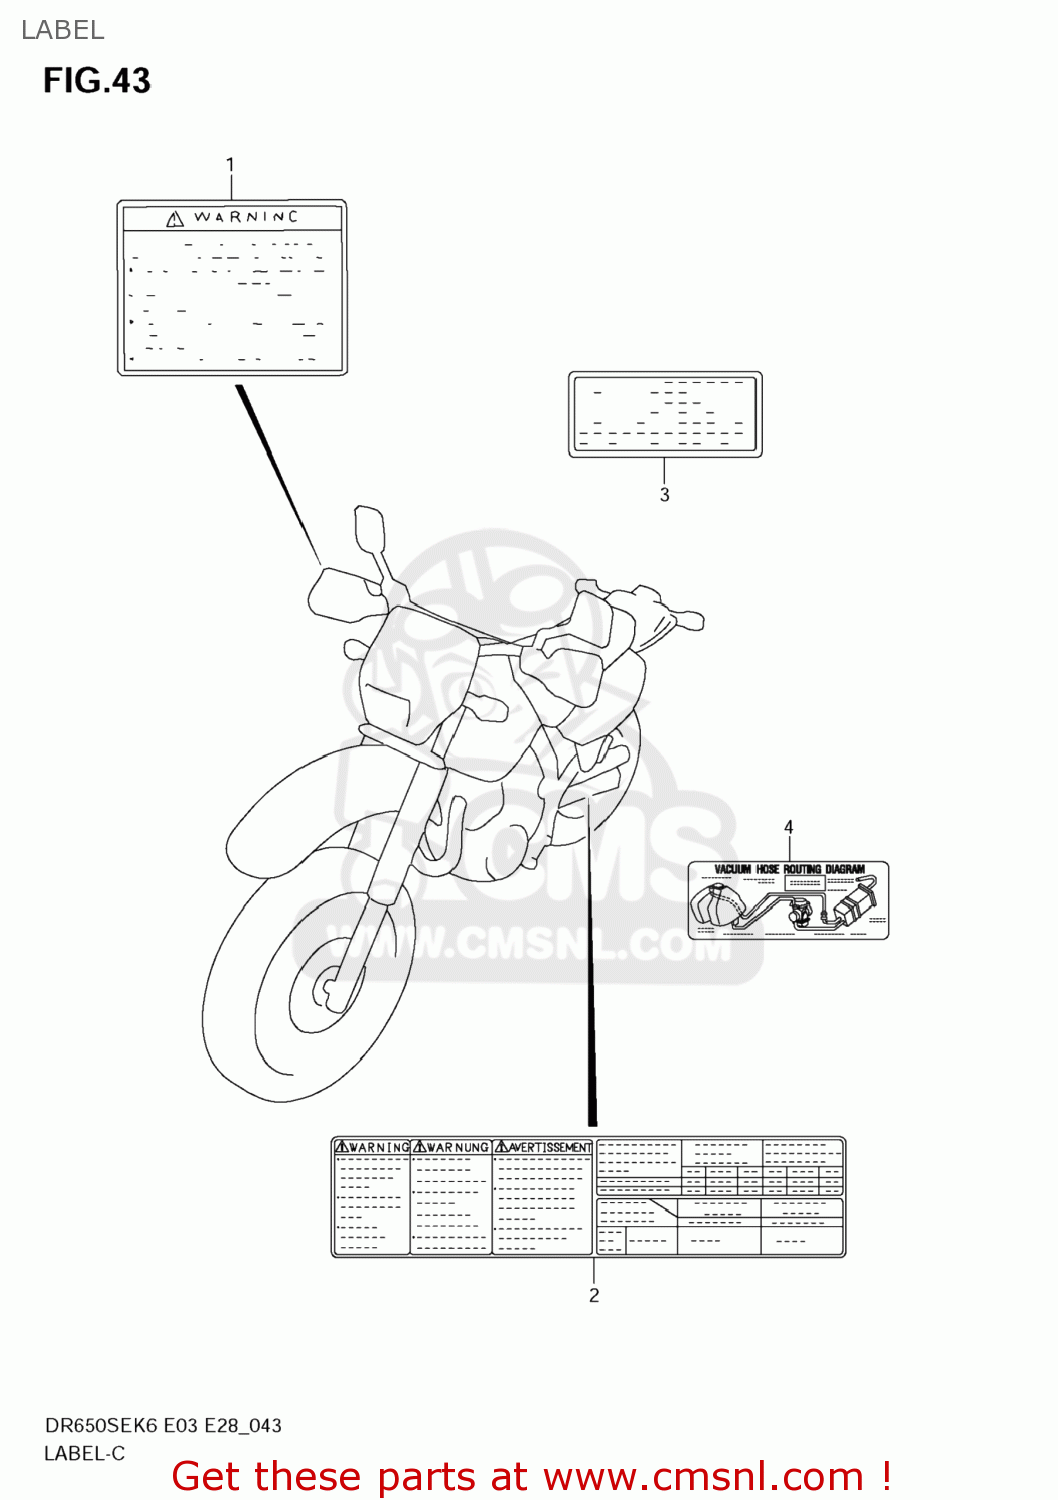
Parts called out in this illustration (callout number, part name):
1	LABEL,GENERAL WARNING
2	LABEL,TIRE INFORMATION
3	LABEL,MANUAL NOTICE
4	LABEL,PIPING DIAG
5	MANUAL,OWNER'S
